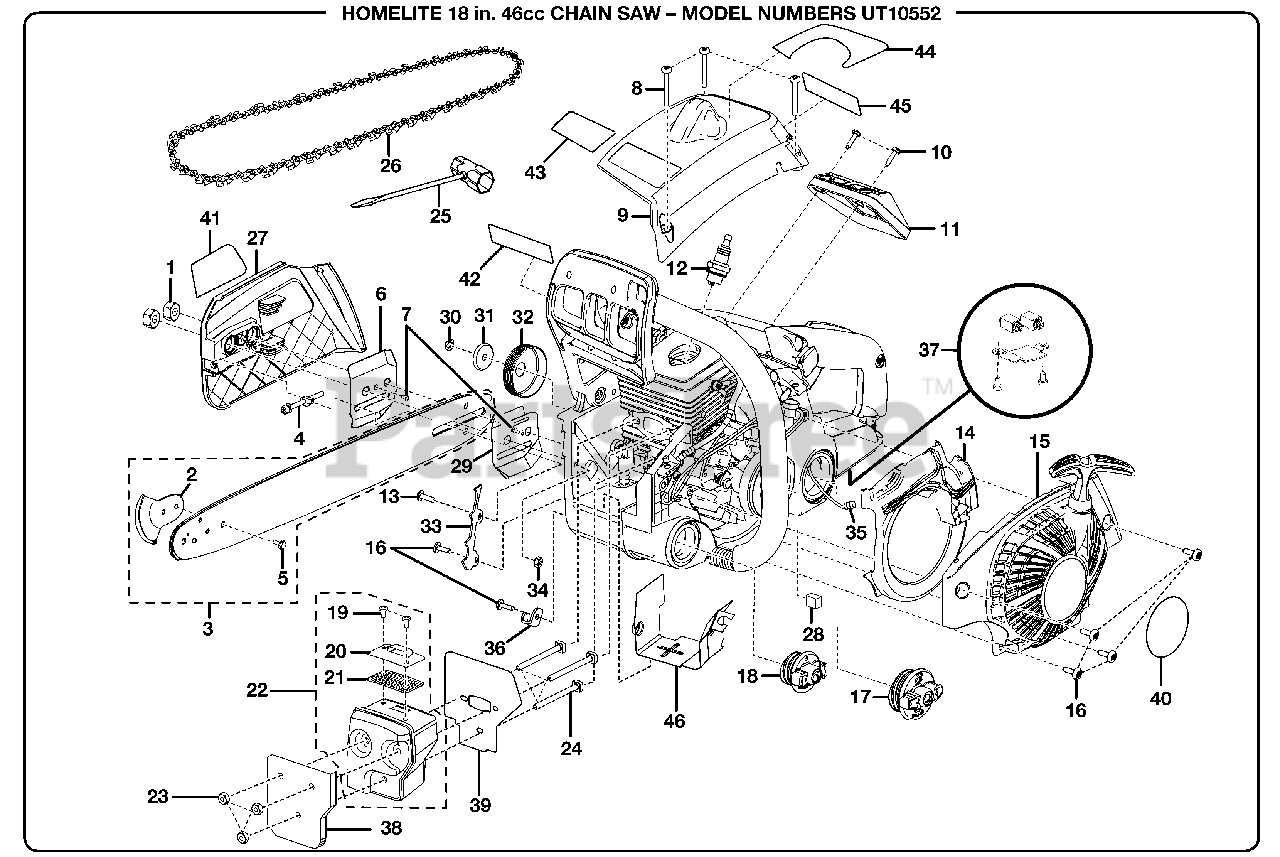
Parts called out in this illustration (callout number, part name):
1	Guide Bar Nut (5/16-18)
3	Guide Bar (16 in.)
4	Guide Bar Adjustment Assembly
5	SAFE-T-TIP (Screw and Washer)
6	Outer Guide Plate
7	Screw (6-19 x 1/2 in. T.F.)
8	Screw (10-16 x 1-1/2 in. Special)
9	Top Cover
10	Screw (8-16 x 16 mm Torx T.F.)
11	Air Filter Cover
12	Spark Plug
13	Screw (10-24 x 5/8 in. Torx Pan Hd.)
15	Starter Cover Assembly
16	Screw (10-14 x 5/8 in. Torx Pan Hd.)
17	Fuel Cap Assembly
18	Oil Cap Assembly
19	Screw (8-32 x 5/16 in.)
21	Spark Screen
22	Muffler Assembly
23	Lock Nut (10-32)
24	Bolt (10-32 x 63.6 mm Square Hd.)
25	Combination Wrench
27	Chain Cover Assembly
28	Pre-Filter
29	Inner Guide Plate
30	E-Ring
31	Cupped Washer
32	Sprocket Drum & Bearing Assembly
33	Bumper Spike
34	Lock Nut (10-24)
35	Fuel Filter
36	Chain Guard
37	Tool Holder Assembly
38	Heat Shield
39	Muffler Gasket
40	Starter Housing Decal
41	Clutch Cover Label
42	Chain Brake Label
43	Warning Label
44	Starting Instruction Decal
45	Icon Warning Label
46	Heat Shield
